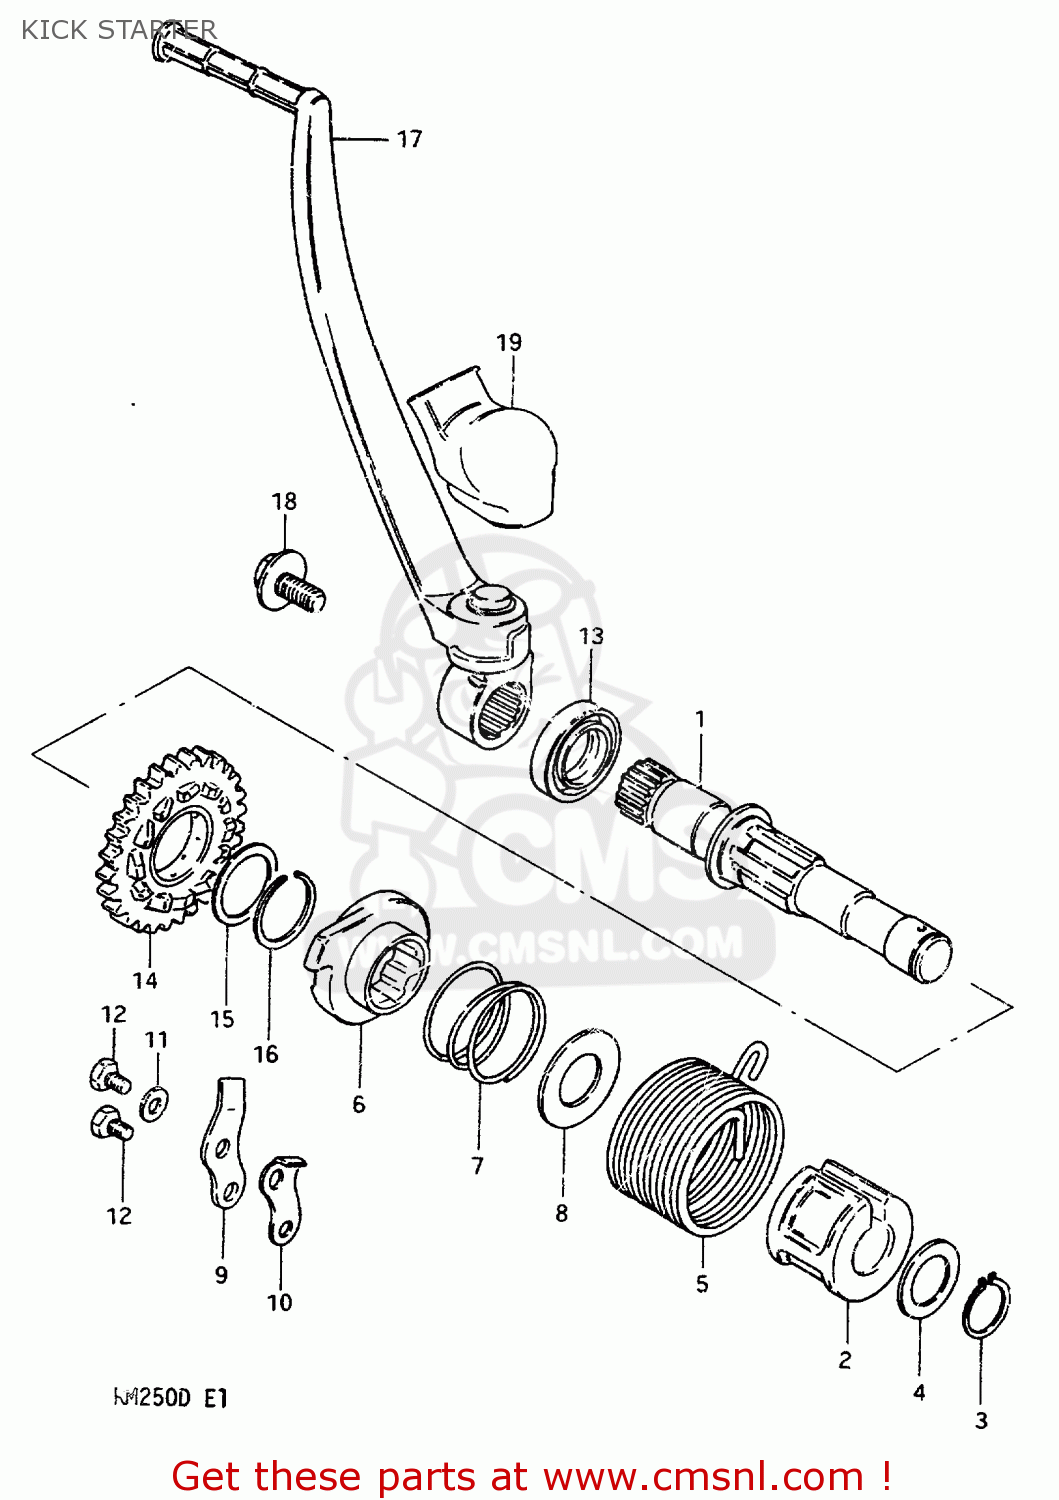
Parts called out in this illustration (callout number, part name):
1	SHAFT,KICK STARTER
2	GUIDE,KICK STARTER SFT SPRING
3	CIRCLIP
4	WASHER
5	SPRING
6	STARTER,KICK
7	SPRING
8	WASHER
9	GUIDE,KICK STARTER
10	STOPPER,KICK STARTER
12	BOLT
13	SEAL,OIL(20X27X5)
14	GEAR
15	SHIM
16	CIRCLIP
17	LEVER ASSEMBLY,KICK STARTER
18	BOLT(8X14)
19	COVER,KICK STARTER LEVER JOINT
